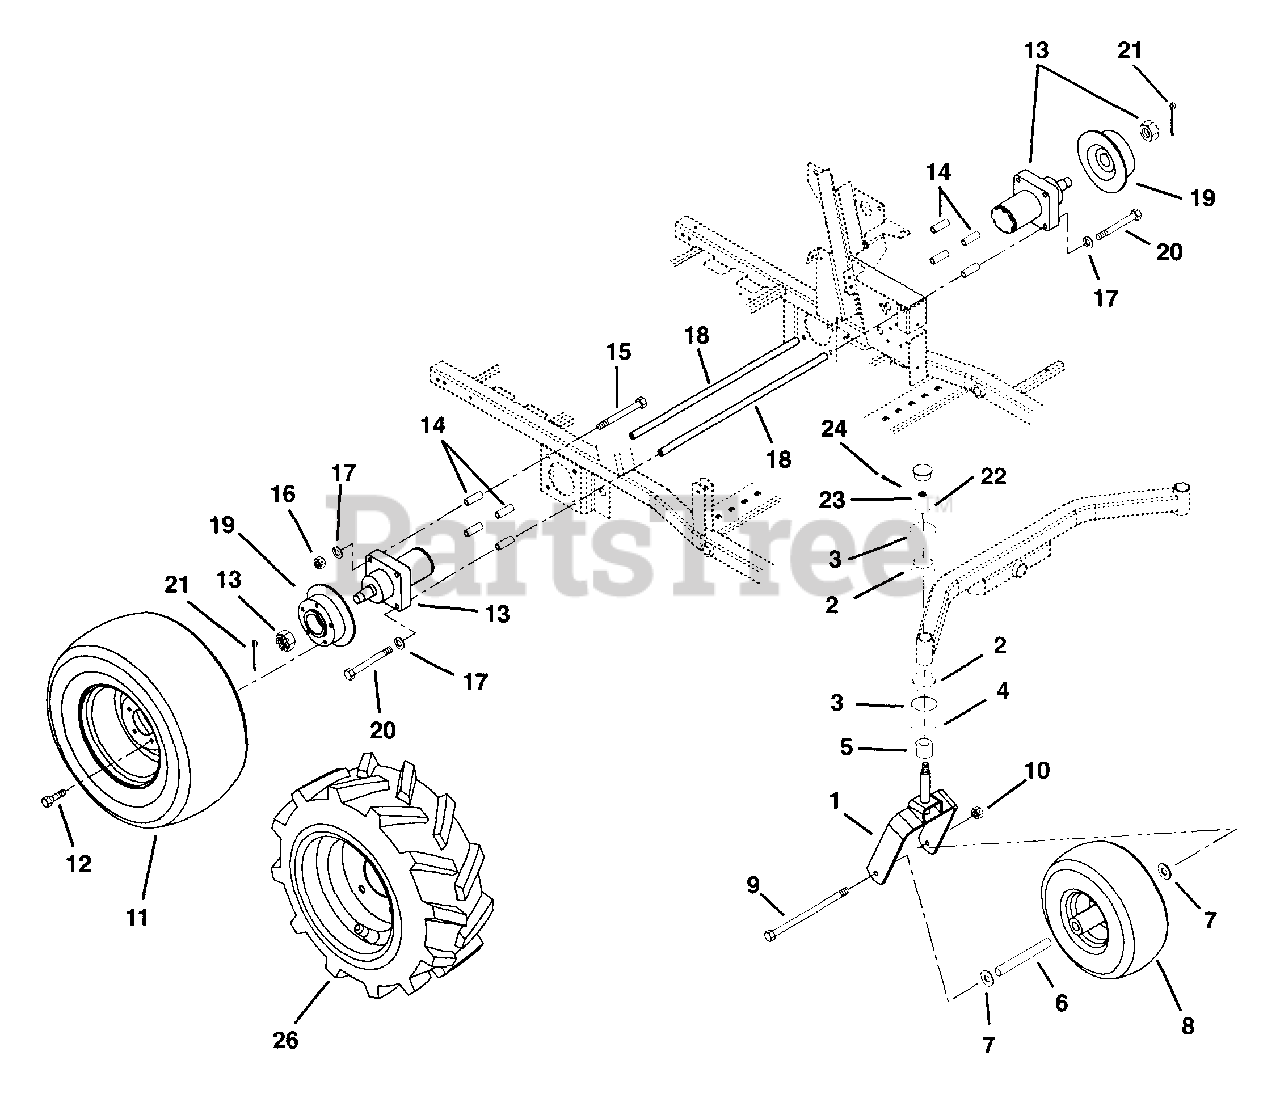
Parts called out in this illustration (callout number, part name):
1	Fork-Front
2	Bearing-Cone 1.0 x .58
3	Bearing-Cup 1.980 x .420
4	Bearing Seal 1.5 x 2 x .18
5	Spacer, PM, 1.03 I.D. x 1.5 O.D. x .375
6	Spacer-Wheel
7	Washer-Flat-Steel .515 x 1.625 x .250
8	Wheel/Tire Assembly
9	Bolt-Hex .50-13 x 9.00 Grade 5
10	Nut-Locking-Center .50-13
11	Wheel-Tire 23 x 10.50 Multi-Trac
12	Bolt-Lug .50-20 x 1.62
13	Hydraulic Wheel Motor
14	Bushing-Sleeve .513 x .748 x 2.129
15	Bolt-Hex .50-13 x 5.00 Grade 5
16	Nut-Locking-Center .50-13
17	Washer-Locking .50 x .125
18	Rod-Motor Connecting
19	Hub and Disc
20	Bolt-Hex .50-13 x 4.50 Grade 5
21	Pin-Cotter .12 x 1.50
22	Washer-Flat-Steel .755 x 1.375 x .062
23	Nut-Slotted .75-16
24	Pin-Cotter .16 x 1.00 EXTPRSQCT
25	Cap-Dust
26	Wheel/Tire Kit, 260Z L. & R.
26	Wheel/Tire-L.H. 23 x 10.5-12 Tru Power
26	Wheel/Tire-R.H. 23 x 10.5-12 Tru Power
